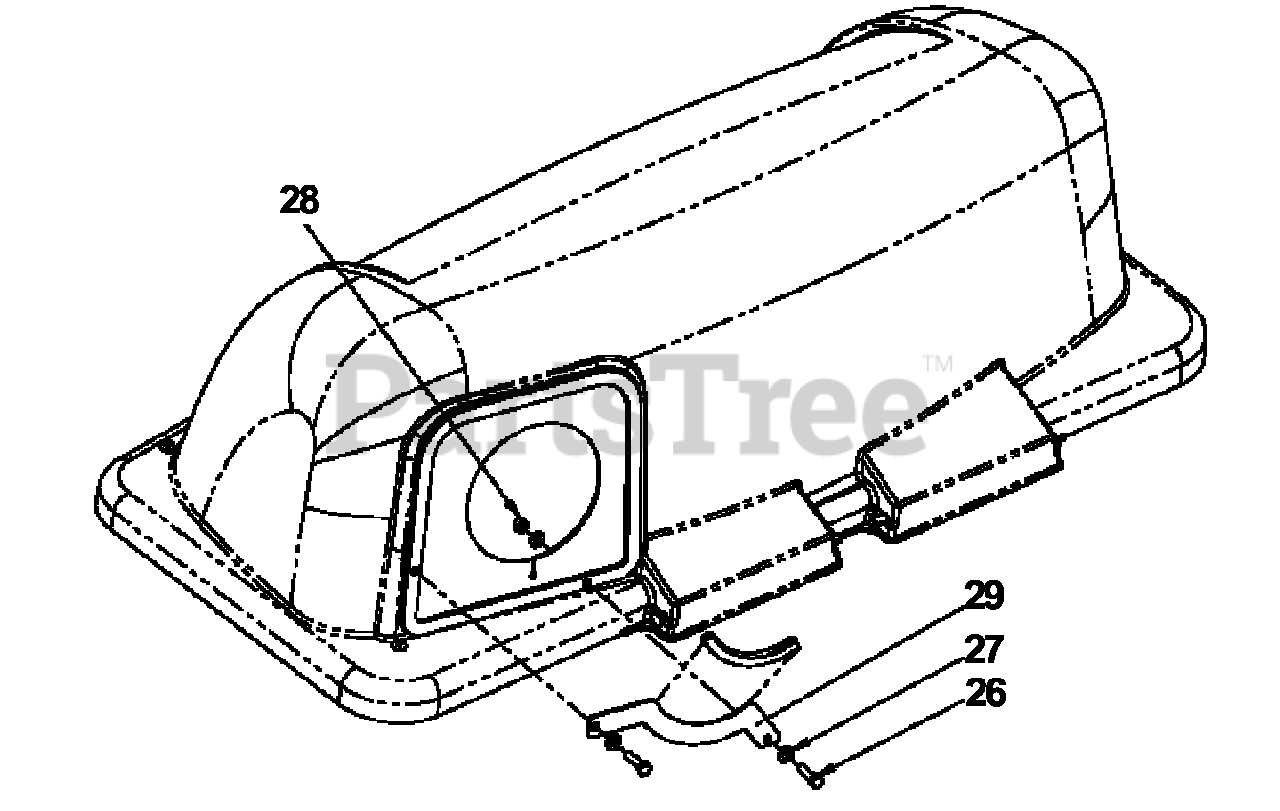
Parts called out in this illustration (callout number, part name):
26	HCS, 5/16-18 x 1 1/4, Gr5
27	Washer, 5/16, SAE
28	Nut, 5/16-18, nyloc
29	Support, chute
